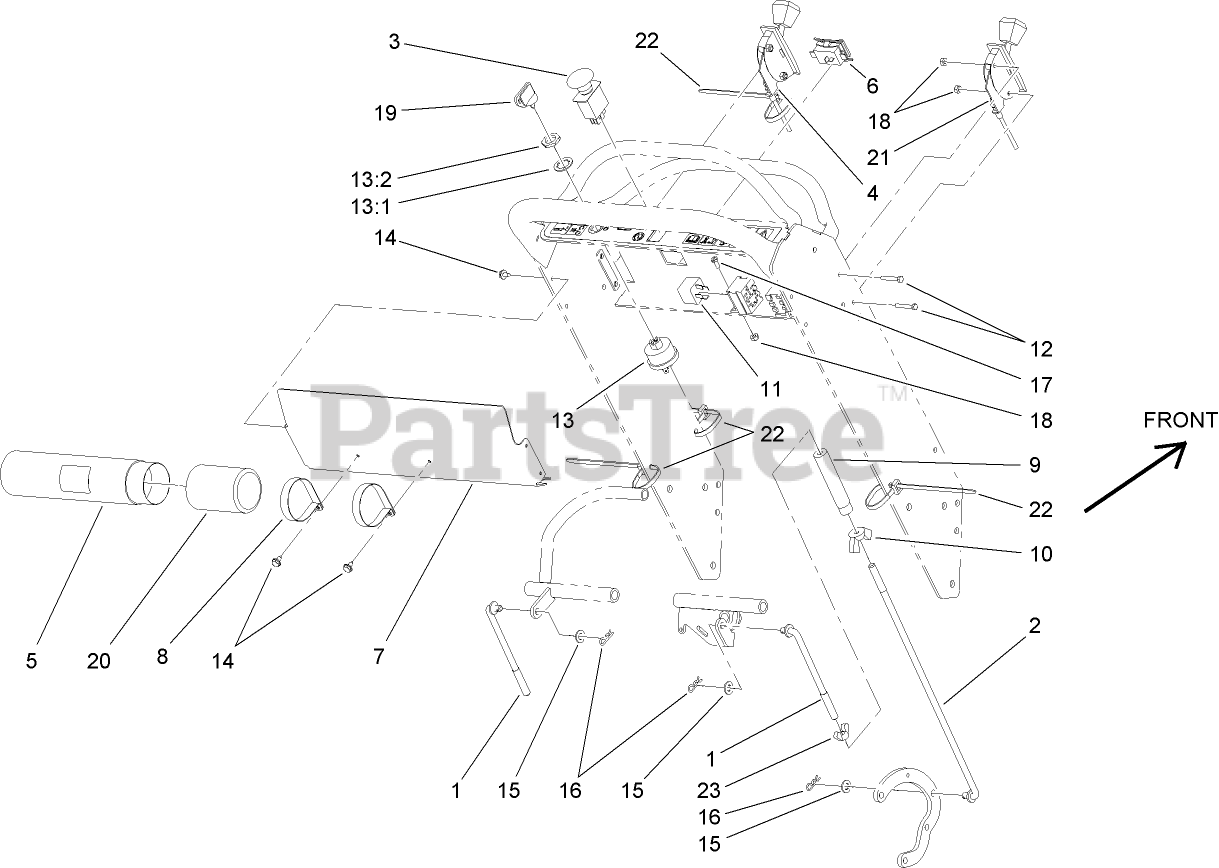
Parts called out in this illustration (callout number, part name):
1	ROD-CONTROL, UPPER
2	ROD-CONTROL, LOWER
3	SWITCH-PTO, ON-ON-(ON)
4	CABLE-THROTTLE
5	TUBE-MANUAL
6	HOURMETER
7	COVER-PANEL, CONTROL
8	CLAMP-R
9	TURNBUCKLE
10	NUT-WING
11	RELAY
12	SCREW-HH
13	Key Switch ASM
13:1	WASHER-TOOTH, INTERNAL
13:2	NUT-HH
14	SCREW-HWHTF
15	WASHER-PLAIN
16	PIN-COTTER
17	SCREW-SHH
18	NUT-LOCK, NI
19	KEY-IGNITION
20	CAP-HOUSING
21	CABLE-CHOKE
22	TIE-CABLE
23	NUT-WING, LH
